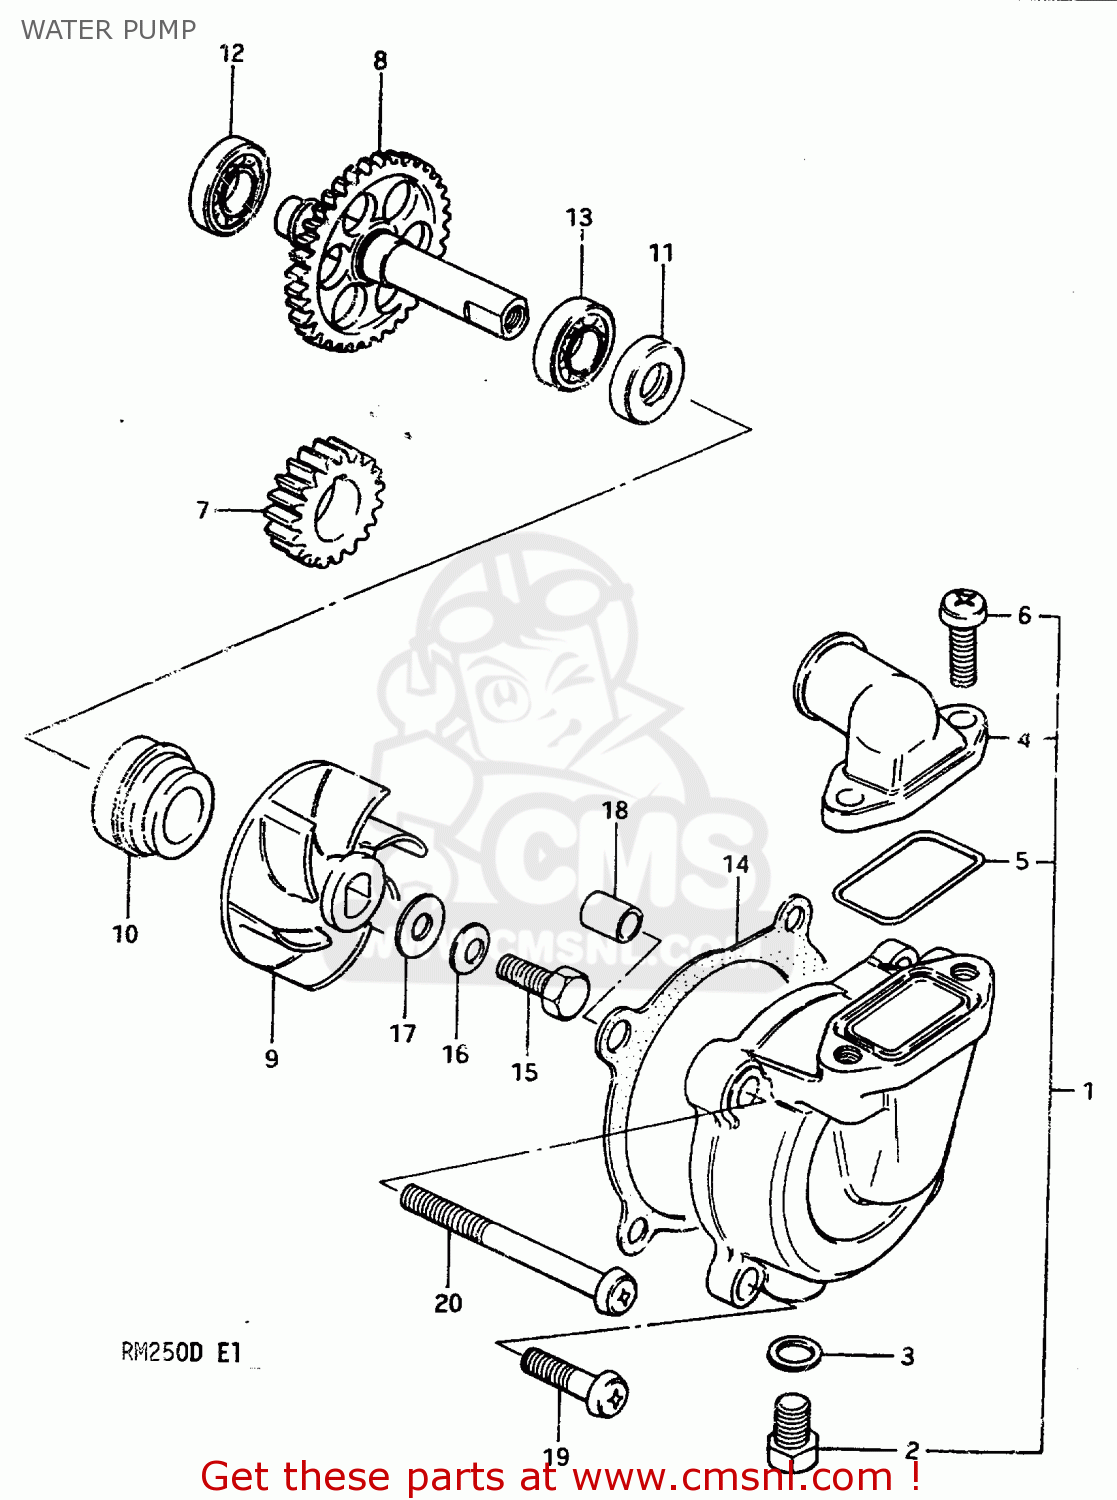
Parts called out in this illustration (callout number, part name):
1	CASE,WATER PUMP
2	BOLT,DRAIN
3	GASKET,DRAIN (NAS)
4	CONNECTOR
5	O RING,WATER PUMP CONNECTOR
6	SCREW
7	GEAR,WATER PUMP DRIVE
8	GEAR,WATER PUMP DRIVEN(NT:36)
9	IMPELLER,WATER PUMP
10	SEAL,WATER PUMP SHAFT
11	SEAL,OIL(10X21X5)
12	BEARING(10X22X6)
13	BEARING
14	GASKET,WATER PUMP CASE (NAS)
15	BOLT(6X13)
16	WASHER
17	GASKET(6X15X2.2) (NAS)
18	PIN
19	SCREW
20	SCREW 6X60
